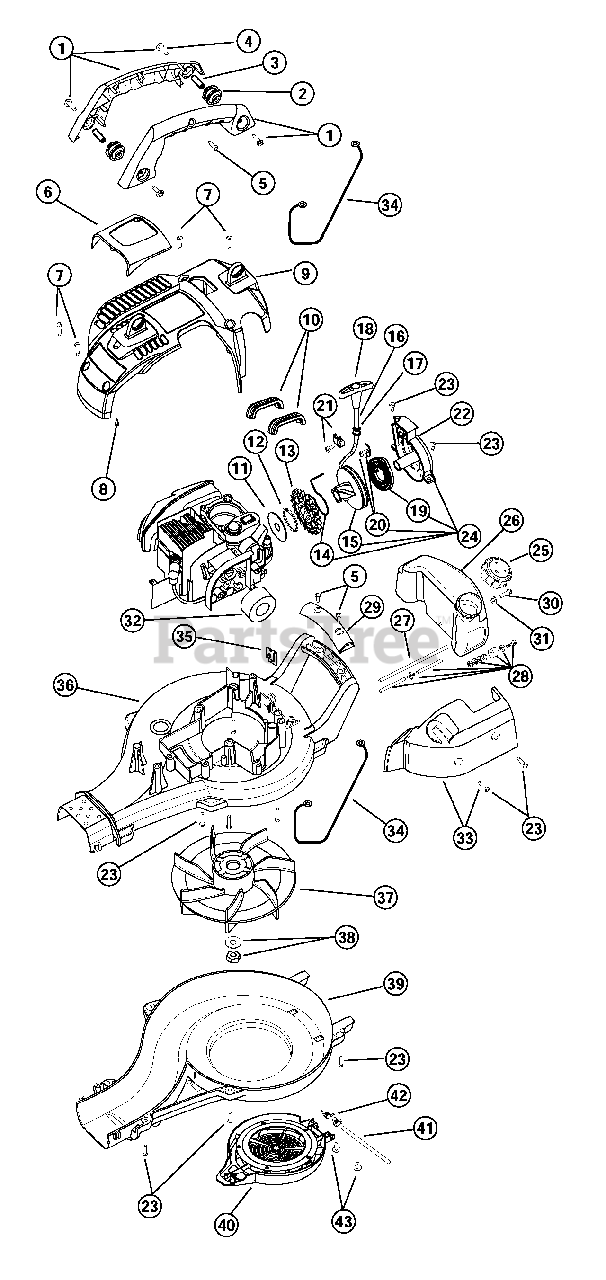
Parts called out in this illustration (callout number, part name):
1	Handle Grip Assembly
2	Vibration Dampner
3	Dampner Spacer
4	Handle Screw
5	Screw
6	Diverter
7	Cover Screw
8	Baffle Screw
9	Engine Cover Assembly
10	Fuel Tank Pad
12	Gear Return Spring
13	Pulley Gear
14	Friction Spring
15	Starter Pulley
17	Rope Guide
18	Pull Handle
19	Rewind Spring
20	Pulley Retainer Assembly
21	Rope Guide Retainer Assembly
22	Recoil Housing
23	Recoil Case Screw
24	Recoil Housing Assembly
25	Fuel Cap
26	Fuel Tank Assembly
27	Fuel Line
28	Fuel Line Assembly
29	Assist Handle
30	Fuel Tank Screw
32	Air Filter Assembly
33	Air Filter Cover
34	Ground Wire
35	Tinnerman Nut
36	Upper Housing Assembly
37	Impeller
38	Washer and Lock Nut Assembly
39	Lower Housing with Insert
40	Vacuum Door Assembly
41	Hinge Shaft
